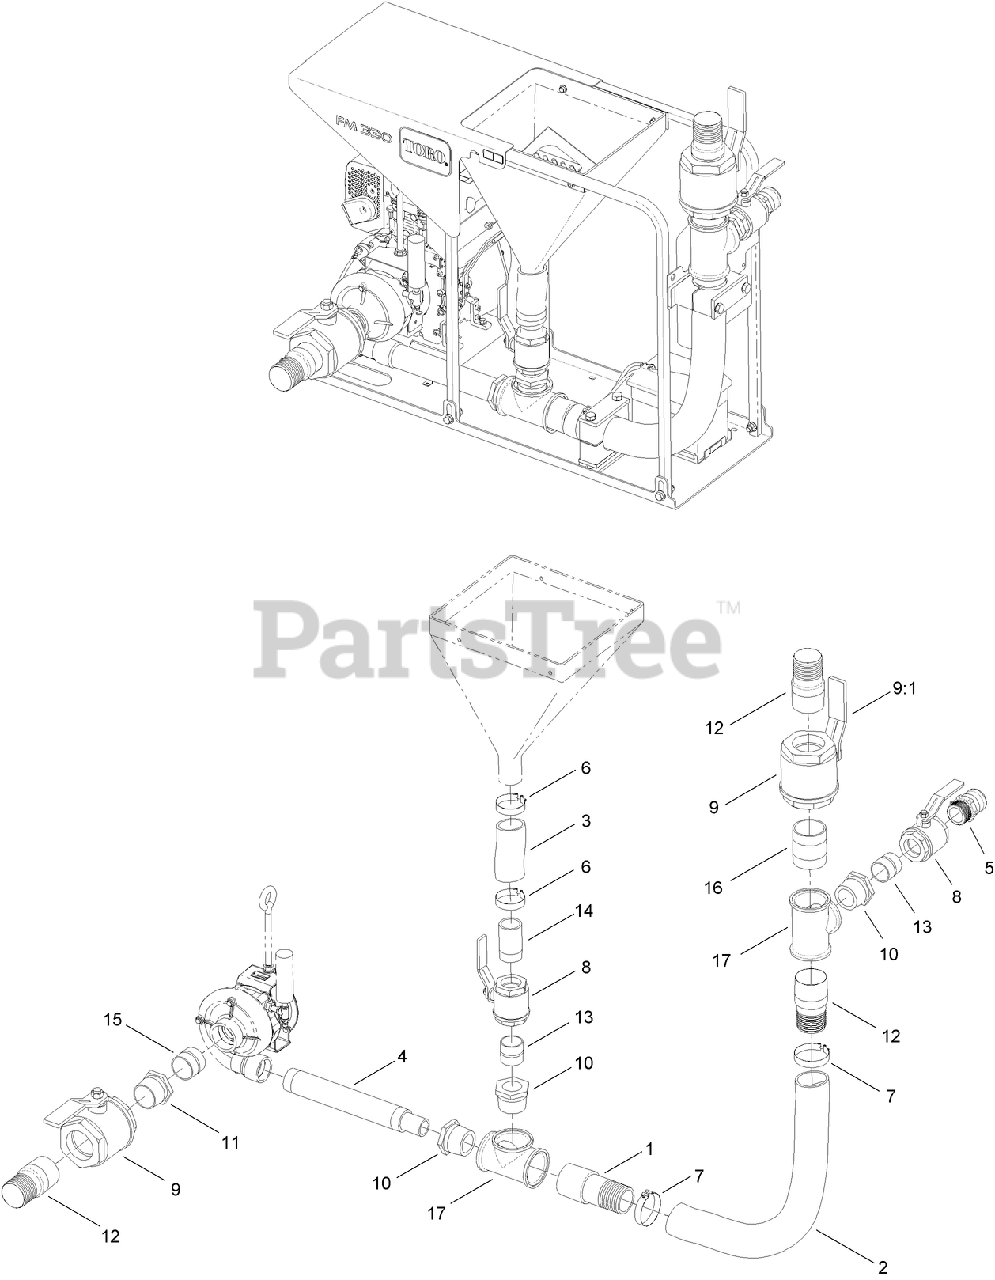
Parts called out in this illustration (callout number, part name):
1	VENTURI
2	HOSE-SUCTION, WATER
3	HOSE-SUCTION, WATER
4	TUBE-JET
5	ADAPTER-MALE
6	CLAMP, T-BOLT
7	CLAMP-T BOLT
8	VALVE-BALL (2.0)
9	VALVE-BALL (3.0)
9:1	HANDLE-BALL, 3.0 VALVE
10	BUSHING-PIPE
11	BUSHING-PIPE
12	NIPPLE-COMBINATION
13	NIPPLE-PIPE
14	NIPPLE-PIPE
15	NIPPLE-PIPE
16	NIPPLE-PIPE
17	TEE-PIPE
